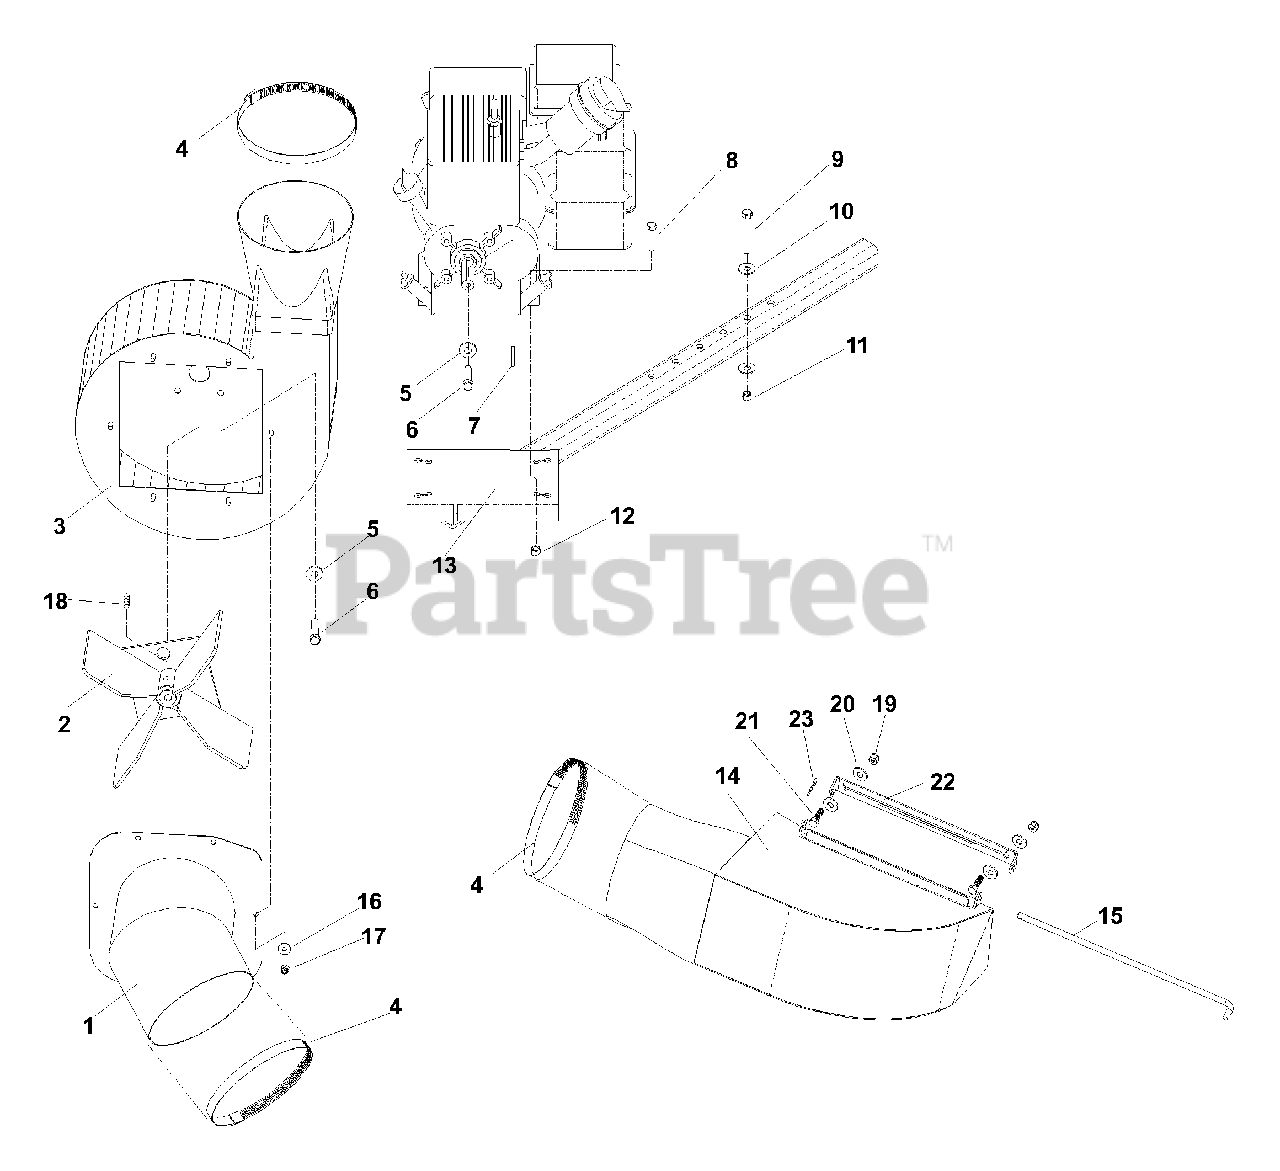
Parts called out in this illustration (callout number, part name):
1	INLET, BLOWER HSG.
3	BLOWER HSG.
4	HOSE CLAMP
5	WASHER 5/16 SPRING
6	BOLT, 5/16-24 X 3/4
7	KEY, 3/16 X 1 3/4 SQ.
8	BOLT, 5/16-18 X 1 1/2
9	BOLT, 3/8-16 X 2 1/2
10	WASHER, 3/8
11	NUT, 3/8-16, NYLOC
12	NUT, 5/16-18, NYLOC
13	ENGINE MOUNT
14	BOOT, GEN II
14	BOOT, GEN I
15	HINGE PIN, 5/16 X 14"
16	WASHER, 1/4
17	NUT, 1/4-20, NYLOC
18	SETSCREW 3/8 X .375
19	NUT, 5/16-18, NYLOC
20	WASHER, 5/16
21	BOLT, 5/16-18 X 1
22	BRACKET
23	COTTER PIN, #13
